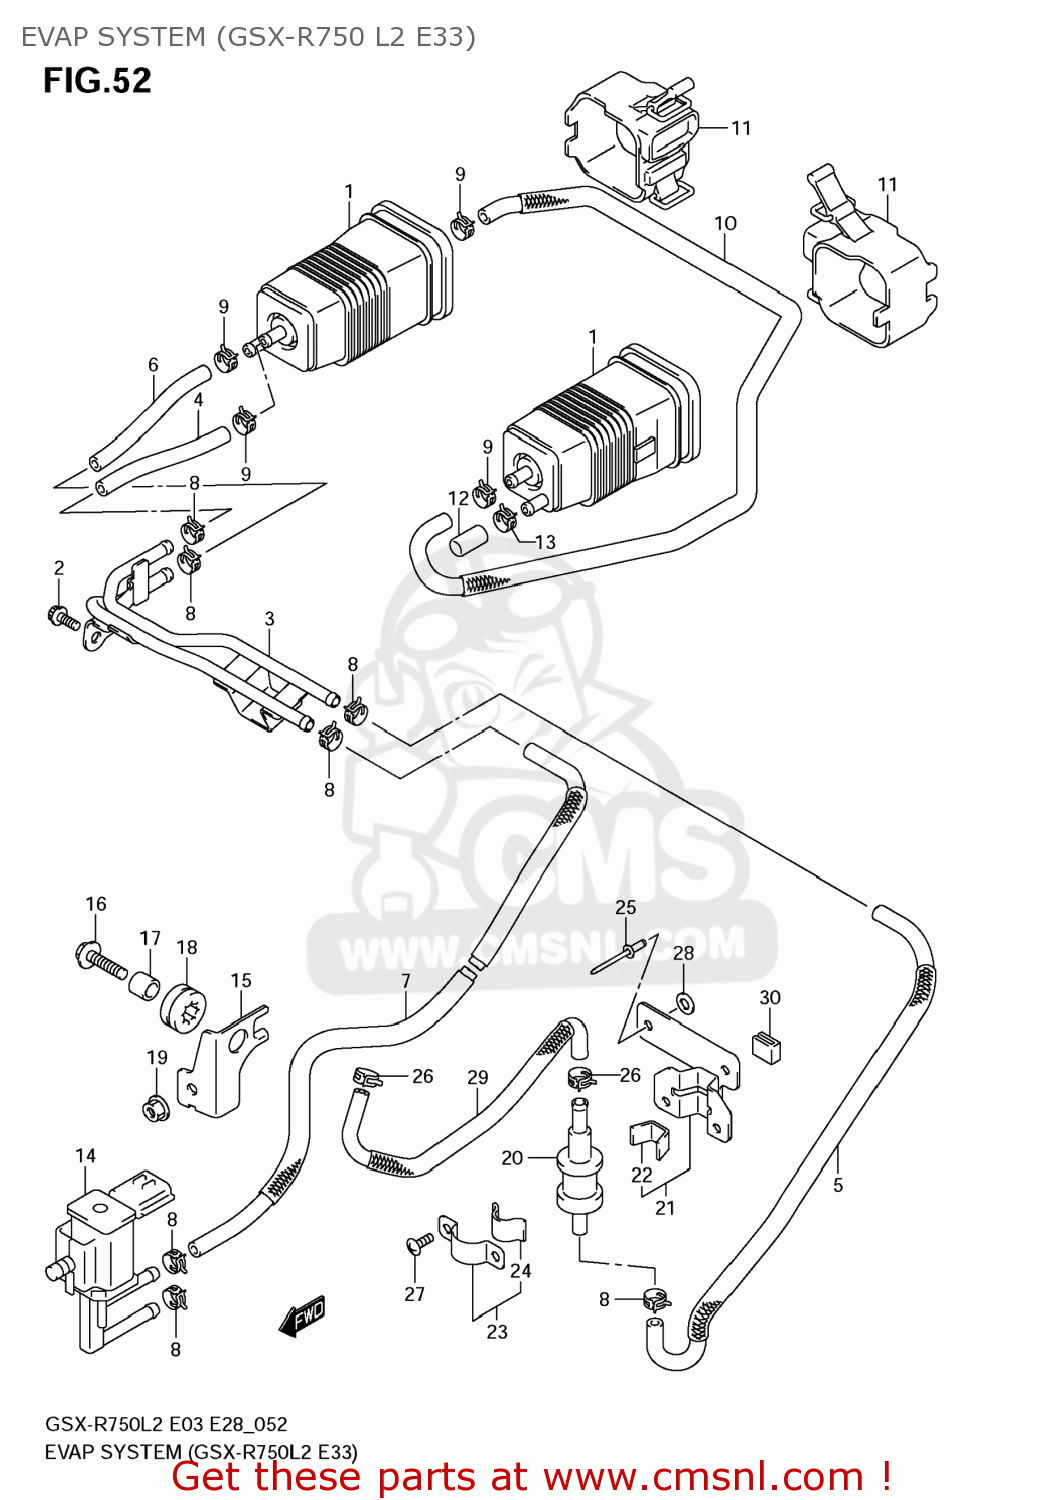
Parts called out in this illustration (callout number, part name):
1	CANISTER ASSY,CHARCOAL
2	BOLT
3	PIPE,EVAP
4	HOSE,SURGE NO.1
5	HOSE,SURGE NO.2
6	HOSE,PURGE NO.1
7	HOSE,PURGE NO.2
8	CLIP
9	CLIP
10	HOSE,CANISTER JOINT
11	CUSHION,CANISTER
12	CAP,OD:11.5
13	CLIP
14	VALVE ASSY,DUTY FOR PURGE
15	BRACKET,PURGE VALVE
16	BOLT(6X30)
17	SPACER(6.5X10X11.6)
18	CUSHION
19	NUT
20	VALVE,FUEL TANK BREATHER
21	PLATE,BREATHER VALVE
22	CUSHION
23	PLATE,FUEL TANK BREATHER NO.2
24	CUSHION
25	RIVET
26	CLIP
27	SCREW
28	WASHER
29	HOSE,TANK & BREATHER VALVE
30	CUSHION
